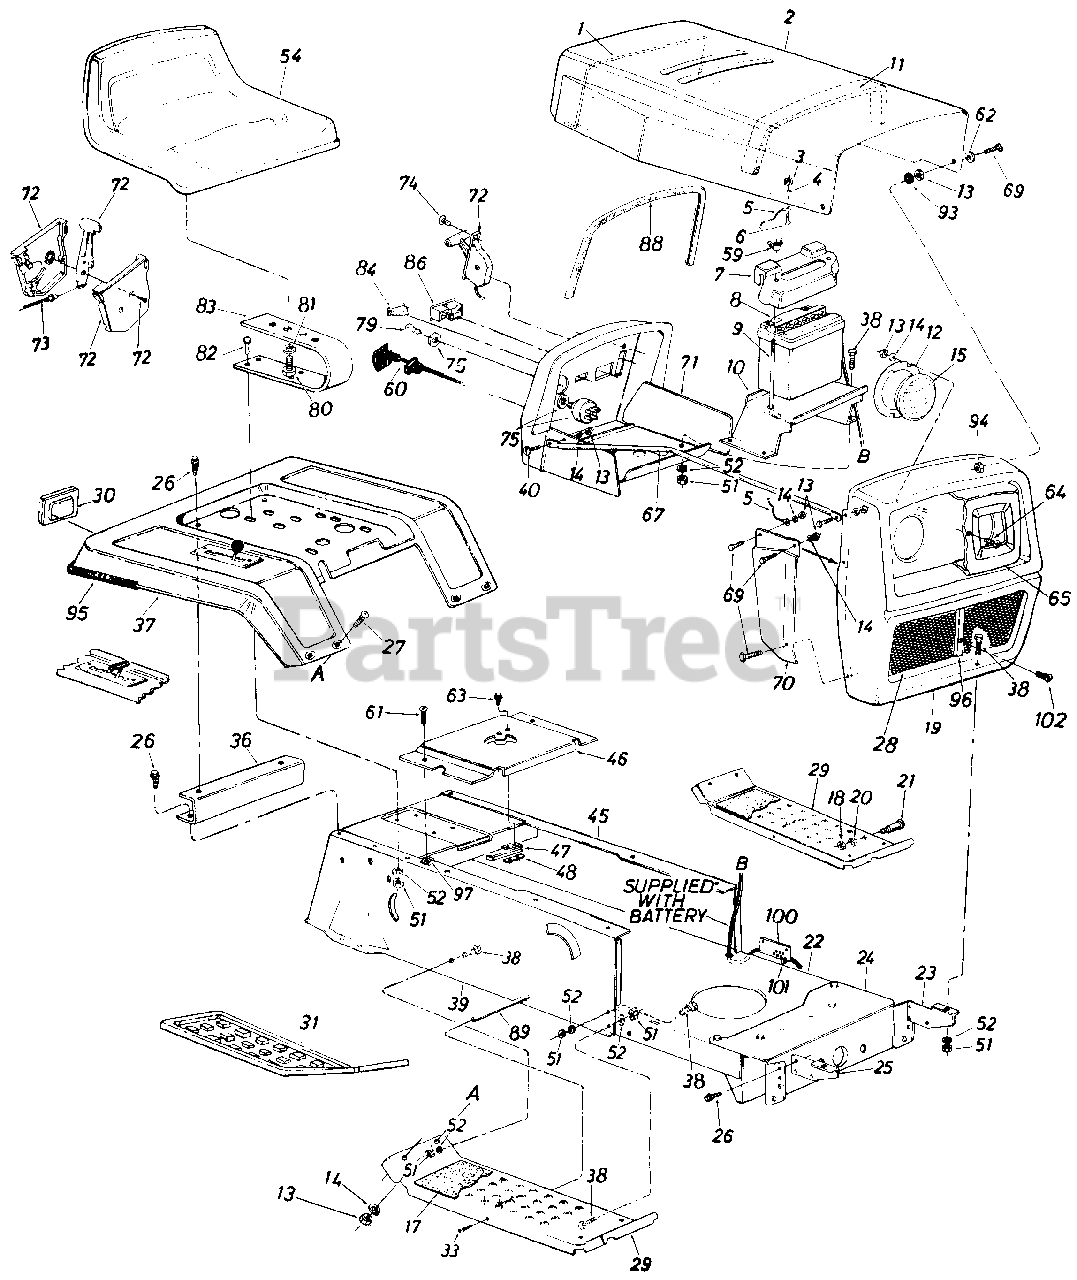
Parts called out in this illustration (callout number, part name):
1	Hood Spring
2	Hood
3	Hex Sems Nut #10-24 Thd.*
4	Push Mount Tie
5	Hood Stop 7" Lg.
6	Truss Hd. Scr. #10-24 x '/2"*
7	Battery Cover
8	12 Volt Battery
9	Battery Hold Down Rod
10	Battery Bracket
11	PVC Foam-Strip
12	Headlight Retainer
13	Hex Nut 1/4-20 Thd.*
14	L-Wash. 1/4" I.D.*
15	Headlight
17	Foot Pad
18	Hex Nut 3/8-16 Thd.*
21	Shld. Bolt .50" Dia. x .84
22	Lower Frame
23	Grille Mount Brkt.-L.H.
24	Front Pivot Brkt.
25	Grille Mount Brkt.-R.H.
26	Hex Wash. Hd. AB-Tap Scr. 5/16 x .75" Lg.
27	Carr. Bolt 1/4-20 x 2.00" Lg.*
29	Running Board
30	Reflector
31	Foot Pad
33	Truss Mach. Scr. 5/16-18 x .75" Lg.*
36	Fender Mount Brace
37	Fender
38	Hex Bolt 5/16-18 x .75" Lg.*
39	R.H. Side Frame
40	Hex Bolt 1/4-20 x .62" Lg.*
45	L.H. Side Frame
46	Shift Cover
47	Reverse Safety Switch
48	Insulator Nut Plate
51	Hex Nut 5/16-18 Thd.*
52	L-Wash. 5/16" I.D.*
54	Seat Ass'y.
59	Wing Nut 1/4-20 Thd.-Plastic
60	Choke Control 44.0" Lg.
61	Truss Mach. Tap Scr. #10 x .50" Lg.
62	Fl-Wash. .281 I.D. x .73 O.D.
63	Hex Wash. Hd. AB-Tap Scr. #8 x .50
64	Truss Hd. Scr. #10-24 x .38" Lg.
65	Bezel
69	Truss Hd. Scr. 1/4-20 x .75" Lg.*
70	R.H.-Grille Side Panel
71	Dash Panel Ass'y.
72	Throttle Control Box Ass'y.
73	Throttle Control Wire-35"
74	Truss Mach. AB-Tap Scr. #10 x .5" Lg.
75	Ignition Switch
79	Ignition Key
80	Hex Bolt 1/2-13 x 1.00" Lg. (Grade 5)
81	L-Wash. 1/2" I.D.
82	Hex Bolt 5/16-18 x 1.00" Lg.*
83	Seat Spring 5.5" High
84	Light Switch
86	Ammeter
88	Molding Strip 27" Lg.
89	Running Board Rod
93	Rubber Wash. 1/2" I.D. x 1.0 O.D. x .25"
94	Hex Sems Ins. L-Nut 1/4-20 Thd.
95	Trim Strip 31.0" Lg.
96	Center Moulding
97	Speed Nut #10Z
100	Brake Cable Bracket
101	Cable Tie
102	Truss Mach. Scr. #10-24 x .62" Lg.
